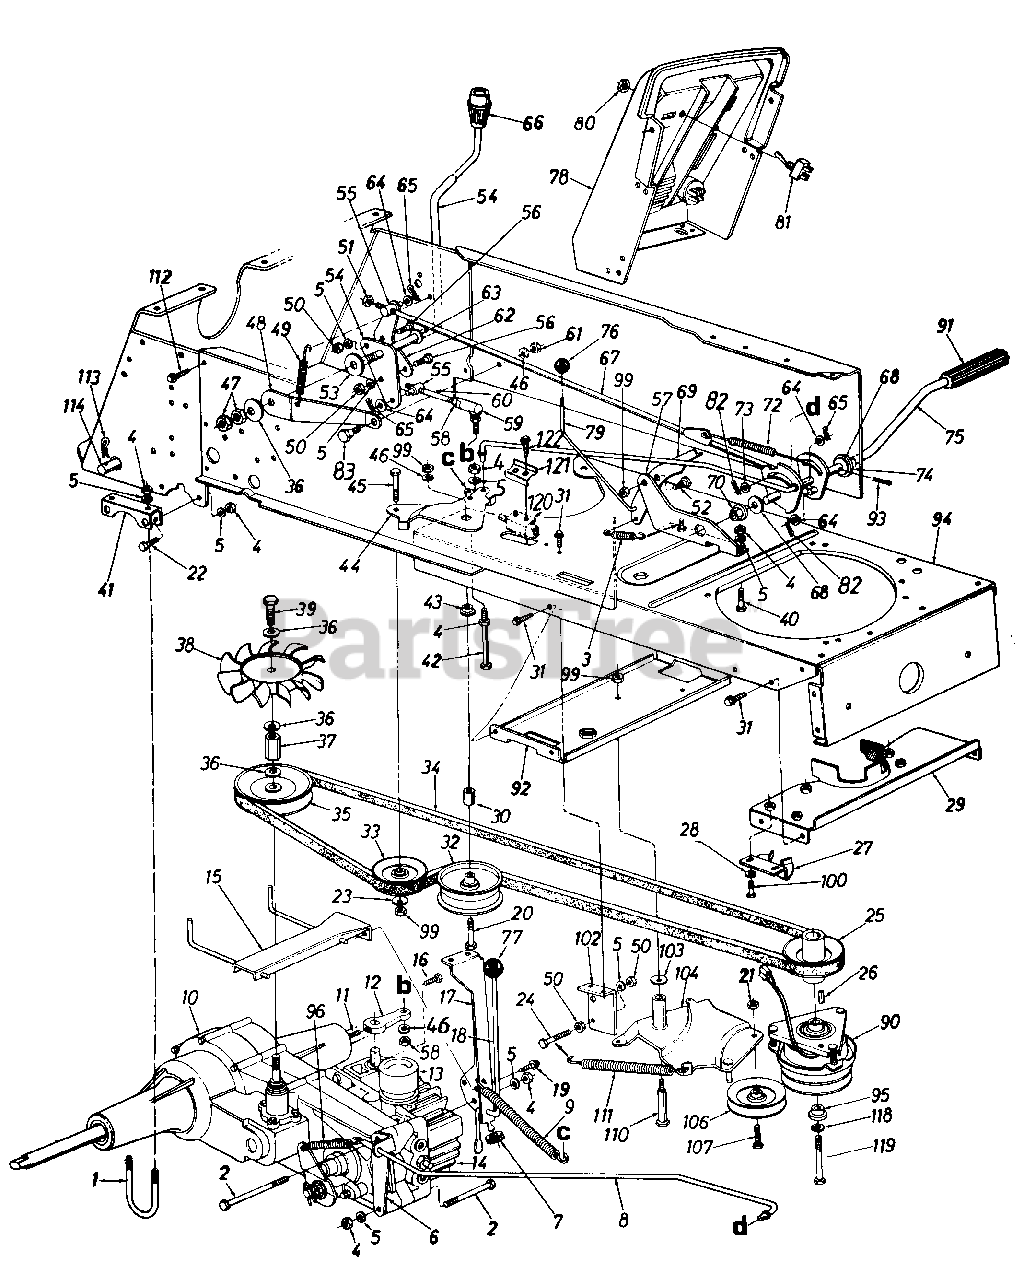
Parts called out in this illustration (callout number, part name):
1	U-Bolt 5/16-18 x 3.25" Lg.
2	Hex Patch Bolt 5/16-18 x 4.5" Lg. (Grade 5)
3	Ext. Spring .5" O.D. x 1.55"
4	Hex Nut 5/16-18 Thd.
5	L-Wash. 5/16" I.D.
6	Brake Rod Guide Brkt.
7	Rubber Wash. .33" I.D. x .87"
8	Brake Rod
9	Ext. Spring .62" O.D. x 6.12" Lg.
10	Transaxle
11	Set Screw 5/16-24 x .38" Lg.
12	Pintle Shift Lever
13	Reservoir
14	Hydrostatic Pump
15	Belt Guard Ass'y.
16	Hex Bolt 5/16-18 x 4.5" Lg. (Grade 5)
17	Transaxle Torque Bracket
18	Transaxle Control Rod
19	Hex Wash. Hd. B-Tap Scr. 5/16-18
20	Hex Bolt 3/8-16 x 2.75" Lg.
21	Hex Cent. Lock Nut 3/8-16 Thd.
22	Hex Bolt 5/16-18 x .75" Lg. (Grade 5)
23	Fl-Wash. 385" I.D. x .87" O.D.
24	Hex Bolt 5/16-24 x 1.75" Lg.
25	Engine Pulley
26	Sq. Key 1/4 x 1" Lg.
29	Belt Keeper Brkt. Ass'y.
30	Spacer .375" I.D. x .75" Lg.
31	Hex Wash. Hd. TT-Tap Scr. 1/4-20 x .5" Lg.
32	Fl-Idler Pulley 3.25" Dia.
33	V-Belt Idler
34	V-Belt
35	Transmission Pulley 4.25" O.D.
36	Bell-Wash. .56" I.D. x 1.5"
37	Fan Adapter Nut 9/16-18 Thd.
39	Hex Bolt 9/16-18 x .5" Lg.
40	Hex Bolt 5/16-18 x .75" Lg.
41	Transaxle Mtg. Bracket
42	Hex Bolt 5/16-18 x 2.75" Lg.
43	Shld. Spacer .625" I.D.
44	Clutch Idler Bracket
45	Hex Bolt 3/8-16 x 1.5" Lg.
46	L-Wash. 3/8" I.D.
47	Hex Jam Nut 1/2-20 Thd.
48	Speed Control Rod Torque Brkt.
49	Ext. Spring 2.5" Lg.
50	Hex Nut 5/16-24 Thd.
51	Hex Jam Nut 3/8-24 Thd.
52	Shld. Bolt .50" Dia. x .170"
53	Fiber Washer .54" I.D. x 1.75"
54	Speed Control Handle Ass'y.
55	Ferrule 3/8-24 Thd.
56	Hex Bolt 5/16-24 x .621 Lg.
57	Foot Pedal Mtg. Brkt.
58	Hex Nut 3/8-24 Thd.
59	Ball Joint Ass'y.
60	Control Rod 3/8-24 x 3.75" Lg.
61	Hex Nut 3/8-16 Thd.
62	Speed Selector Handle Brkt.
63	Fl-Wash. .531" I.D. x 1.25" O.D.
64	Fl-Wash. .885" I.D. x .62" O.D.
65	Internal Cotter Pin
66	Shift Knob
67	Neutral Return Rod
68	Fl-Wash. .64" I.D. x 1.24" O.D.
69	Parking Brake Lock Brkt.
70	Hex Flange Brg. 634" Dia.
72	Extension Spring 3" Lg.
73	Fl-Wash. .344" I.D. x .62" O.D.
74	Flange Bearing w/Flats
75	Foot Pedal Ass'y.
76	Ball Knob Brake
77	Ball Knob 1/4-20 Thd.
78	Dash Panel Ass'y.
79	Parking Brake Link
80	Hex Nut 1/2-27 Thd.
81	Toggle Switch
82	Cotter Pin 31321' Dia. x 1.0" Lg.
83	Shld. Bolt ,5" Dia. x .21 2"
90	Electric Clutch
91	Foot Pad
92	Deck Idler Support Brkt.
93	Cotter Pin 1/8" Dia.
94	Lower Frame
95	Shoulder Spacer
96	Ext. Spring 3.675" Lg.
99	Hex Cent. L-Nut 3/8-16 Thd.
100	Hex Bolt 5/16-18 x .75" Lg. (Grade 5
102	Parking Brake Mtg. Brkt.
103	Bell-Wash. 380" I.D. x .88" O.D.
104	Idler Brkt. Deck Ass'y.
106	V-Belt Idler
107	Hex Bolt 3/8-24 x 1.5" Lg.
110	Shld. Bolt 498" Dia. x 2 05"
111	Ext. Spring 4 on Lg.
112	Hex Wash. AB-Tap Scr. 5/16 x .75" Lg.
113	Hitch Pin Clip
114	Hitch Rod
118	L-Wash. 7/16" I.D.
119	Hex Bolt 7/16-20 x 3.75" Lg.
120	Safety Switch
121	Switch Plate
122	Torx Hd. Mach. B-Tap Scr
